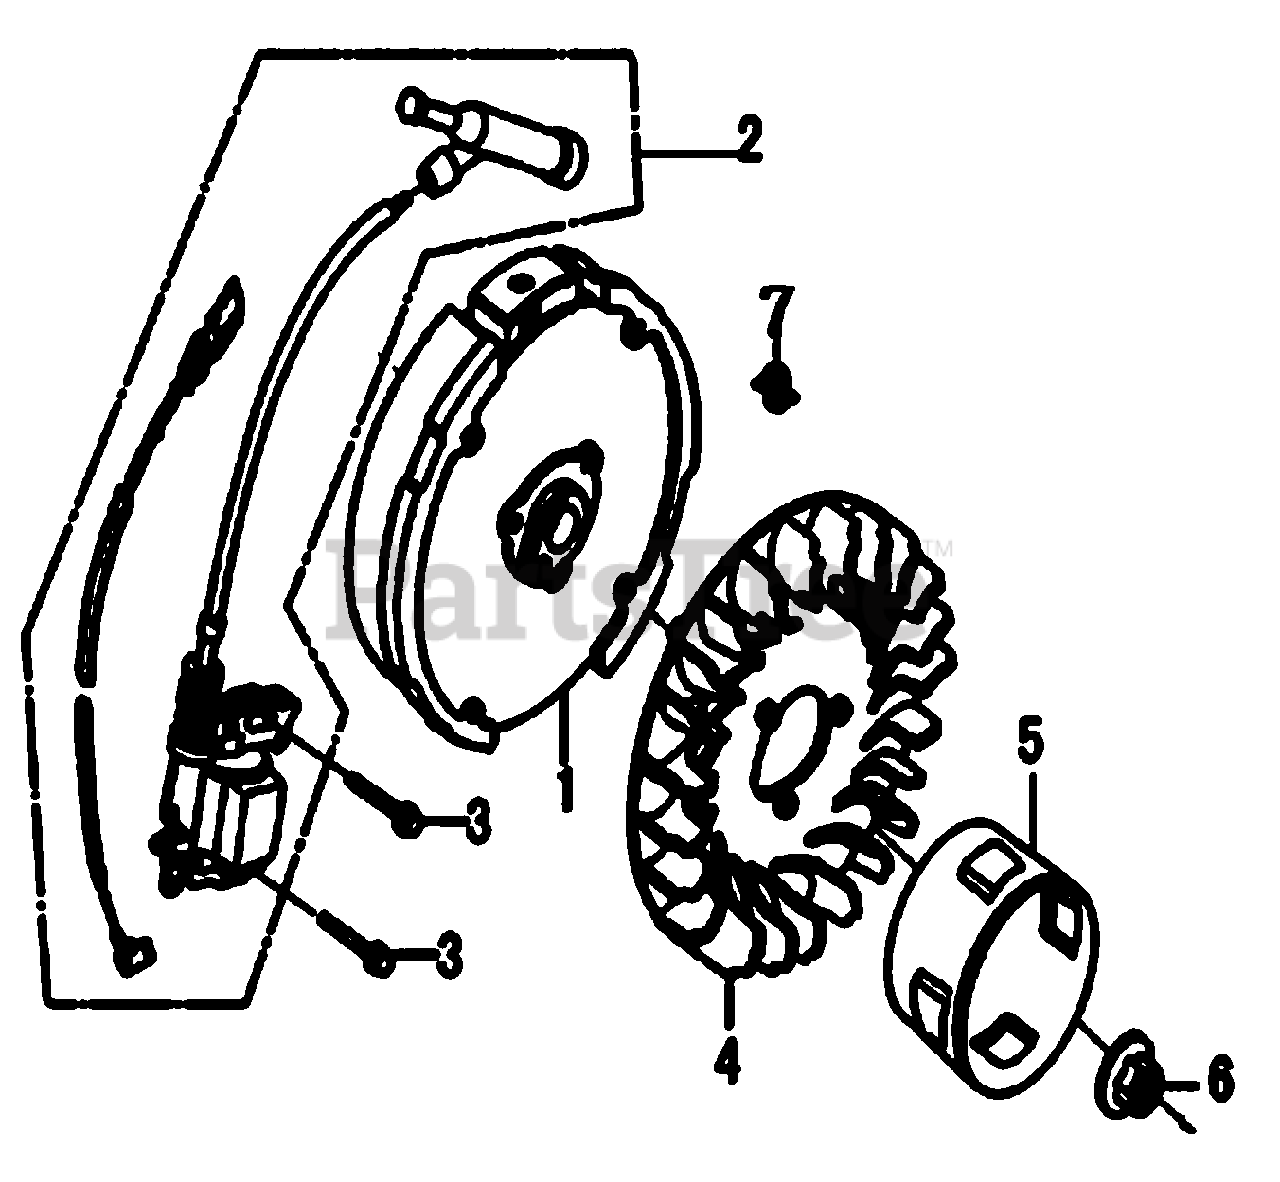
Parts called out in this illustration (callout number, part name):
2	COIL ASSY.,IGNITION
3	BOLT, FLANGE,6X25
4	FAN, COOLING
5	PULLEY, STARTER
6	NUT, SPECIAL
7	CABLE CLIP
